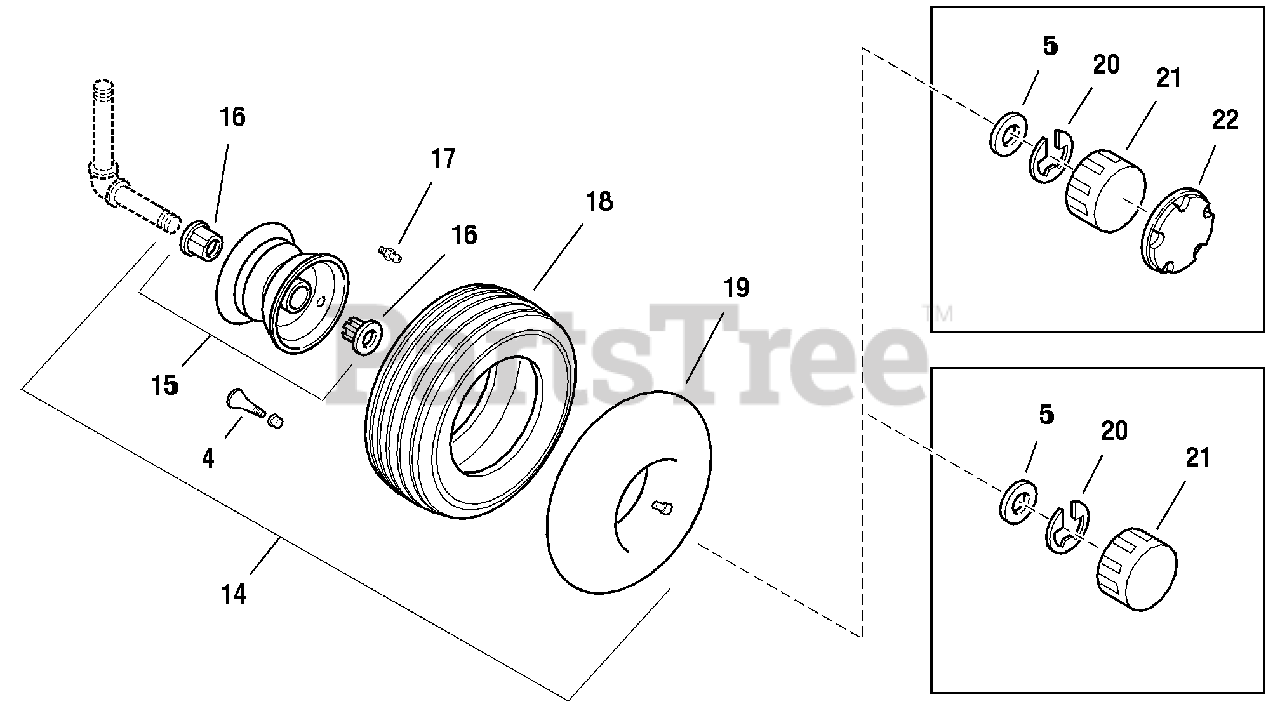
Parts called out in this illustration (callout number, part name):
4	VALVE STEM & CAP
5	WASHER, 3/4
14	FRONT WHEEL & TIRE ASSY.,13 x 5.00-6, Metallic Gray
15	FRONT WHEEL ASSY.,13 x 5.00-6, Metallic Gray
16	BUSHING, Metal, 7-21/32 I.D.
17	Grease Fitting
18	TIRE, Front Wheel, 13 x 5.00-6
19	TUBE, Front Wheel, 4.10/3.50 x 6
21	CAP, Threaded
22	HUB CAP, 6", Scalloped
